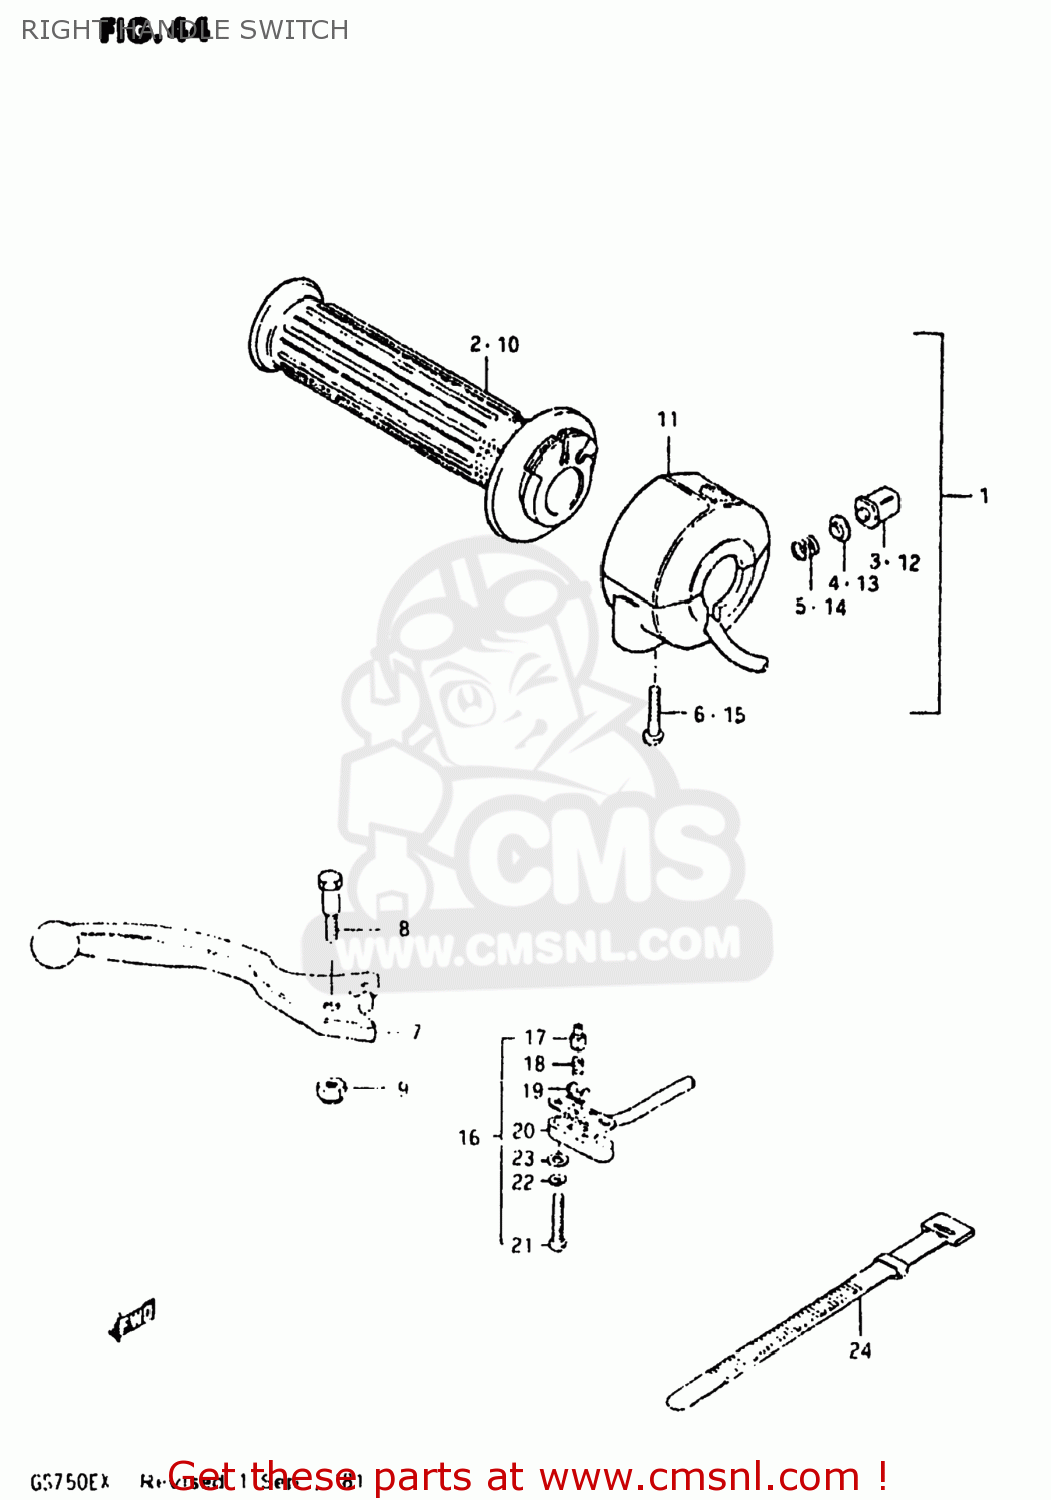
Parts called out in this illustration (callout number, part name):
1	CASE ASSEMBLY,THROTTLE
2	GRIP,THROTTLE
3	BUTTON,HORN
4	CONTACT
5	SPRING
6	SCREW
7	LEVER,BRAKE
8	BOLT
9	NUT 6MM
10	GRIP,THROTTLE
11	CASE ASSEMBLY,THROTTLE
12	BUTTON,HORN
13	CONTACT
14	SPRING
15	SCREW
16	SWITCH ASSEMBLY
17	HOLDER
18	SPRING
19	PLATE
20	COVER,FR BK TERMINAL BASE
21	SCREW
22	LOCK WASHER
23	WASHER
24	CLAMP(L:120)
